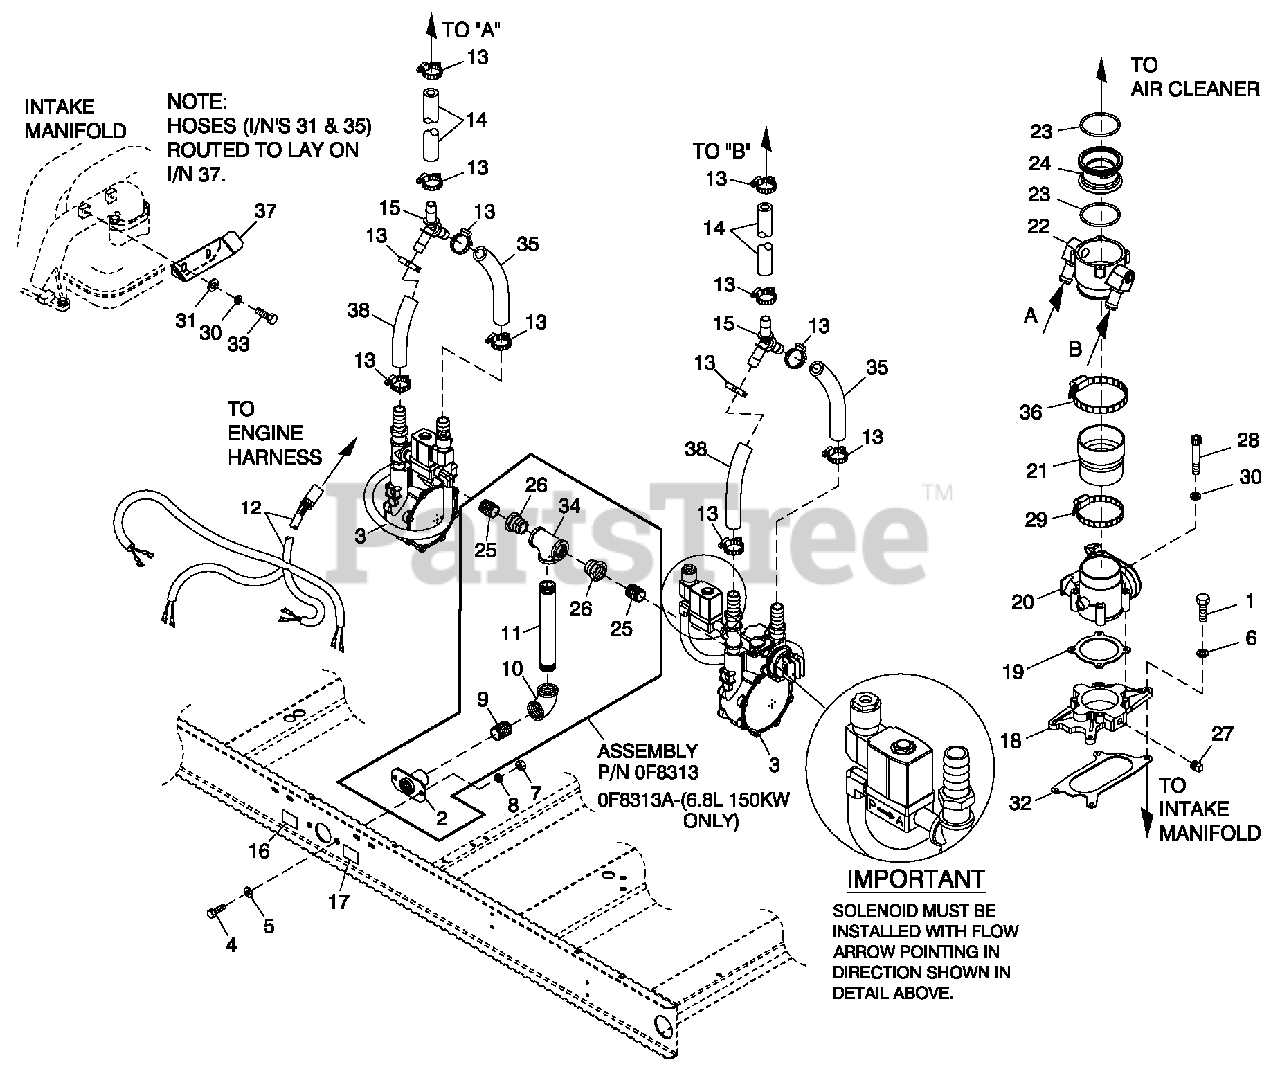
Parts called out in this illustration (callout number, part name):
1	SCREW HHC 5/16-18 X 1-1/4 G5
2	SUPPORT NAT GAS SOLENOID
3	REG ASSY 6.8L 130 KW DUAL NG QT
4	SCREW HHC $12-1.75 X 20 G8.8
5	WASHER FLAT 1/2 ZINC
6	WASHER LOCK M8-5/16
7	NUT HEX M12-1.75 G8 YEL CHR
8	WASHER LOCK 1/2
9	NIPPLE CLOSE 1.25 NPT X 1.625
10	ELBOW 90D1-1/4 NPT
11	NIPPLE PIPE 1-1/4 NPT X 3 (130 KW)
12	HARNESS, FUEL JUMPER DUAL REG
13	CLAMP HOSE #8 .53-1.00
14	HOSE 3/4 ID SAE-30R2 (42" LG)
15	Y CONNECTOR 500 SERIES BARBS
16	DECAL INLET PRESSURE
17	DECAL FUEL INLET NG
18	ADAPTOR THROTTLE BODY
19	GAS KET GOVERNOR ACTUATOR
20	ACTUATOR BOSCH 60 GOVERNOR
21	REDUCER 3.0" TO 2.75" TURBO
22	MIXER 40/60MM ACTUATOR ASSY
23	O-RING 2-3/4X3/32X2-15/16
24	VENTURI THROTTLE 44MM (130KW)
25	NIPPLE CLOSE 3/4X1.375
26	BSHG RDCR HEX1-1/4-3/4
27	PLUG STD PIPE 1/4 STEEL SQ HD
28	SCREW SHC M6-1.0 X 45 G12.9
29	CLAMP HOSE #44 2.31-3.25
30	WASHER LOCK M6-1/4
31	WASHER FLAT M6
32	GAS KET ADAPTER THROT BODY
33	SCREW HHC M6-1.0X 20 G8.8
34	PIPE TEE 1-1/4 NPT
35	HOSE 3/4 ID SAE-30R2 (12" LG)
36	CLAMP HOSE #52 2.81-3.75
37	BRAC KET, HOSE RISER
38	HOSE 3/4 ID SAE-30R2 (9.5" LG)
